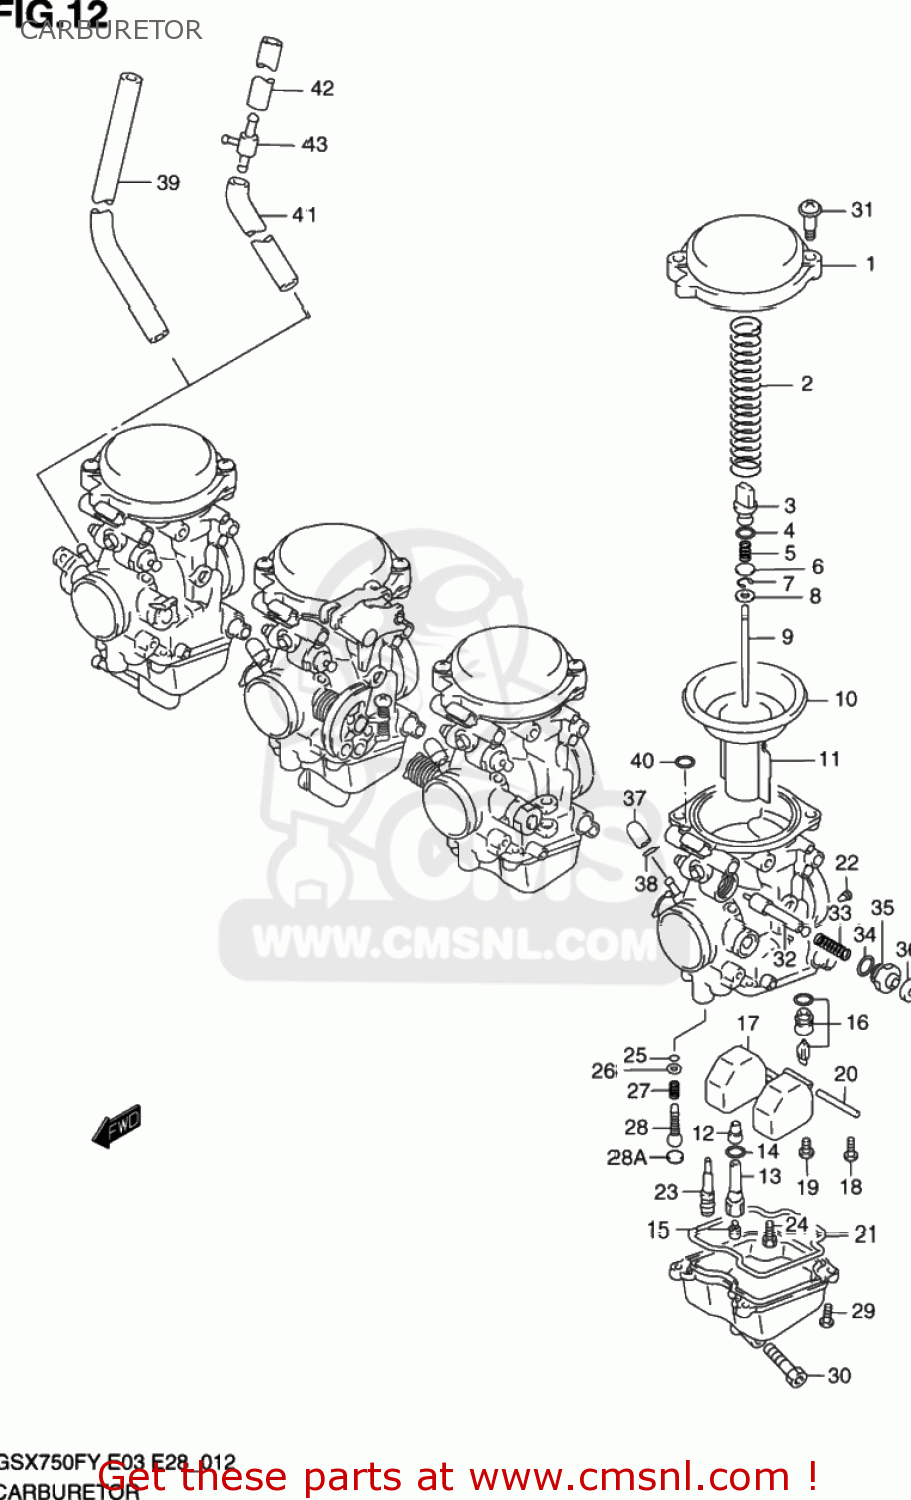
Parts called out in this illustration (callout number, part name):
1	COVER,DIAPHRAGM
2	SPRING
3	HOLDER
4	O RING(D:1.9,ID:4.8)
5	SPRING
6	WASHER
7	E RING,MULTIPLE JET NOZZLE
8	RING
9	NEEDLE,JET
10	DIAPHRAGM
11	VALVE,PISTON
12	JET,NEEDLE(P-0M)
13	HOLDER,JET
14	O RING
15	JET,MAIN
16	VALVE ASSY,NEEDLE
17	FLOAT ASSY
18	SCREW
19	SCREW
20	PIN,FLOAT
21	GASKET (NAS)
22	JET,POWER(130)
23	JET,PILOT(12.5)
24	JET,STARTER(50)
25	O RING,PILOT AIR SCREW
26	WASHER
27	SPRING,THROTTLE SCREW
28	ADJUSTER
28A	PLUG
29	SCREW
30	SCREW,DRAIN
31	SCREW
32	PLUNGER
33	SPRING
34	O RING
35	GUIDE SCREW,PLUNGER
36	CAP,STARTER VALVE
37	CAP
38	CLIP
39	HOSE
40	O RING
41	HOSE
42	HOSE
43	NIPPLE
